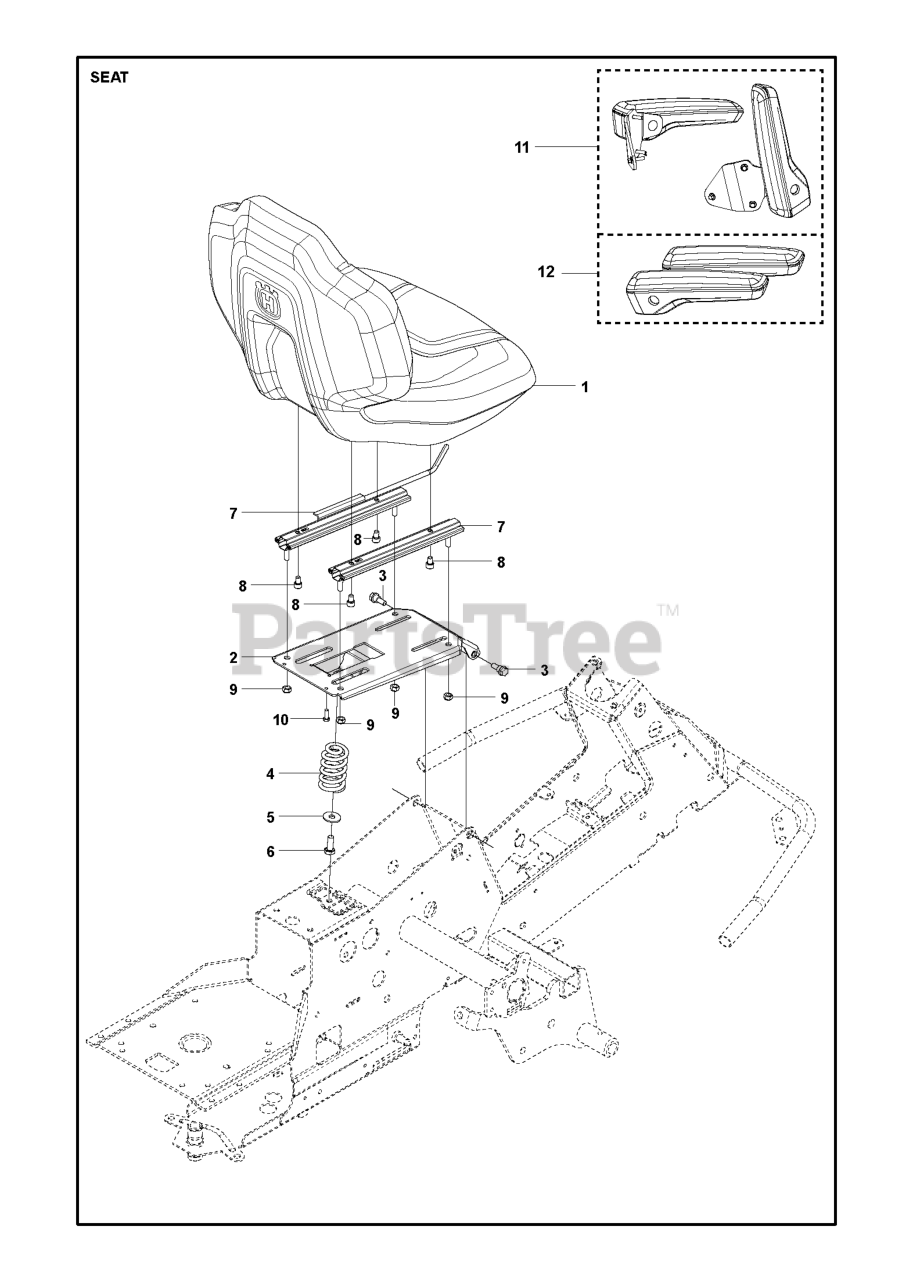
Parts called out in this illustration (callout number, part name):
2	SEAT BRACKET ASSY
4	SEAT SPRING
6	Screw M10x25
7	SEAT ADJUSTER LEFT & RIGHT
8	SCREW IHSCM
9	LOCKNUT M8
10	SCREW
